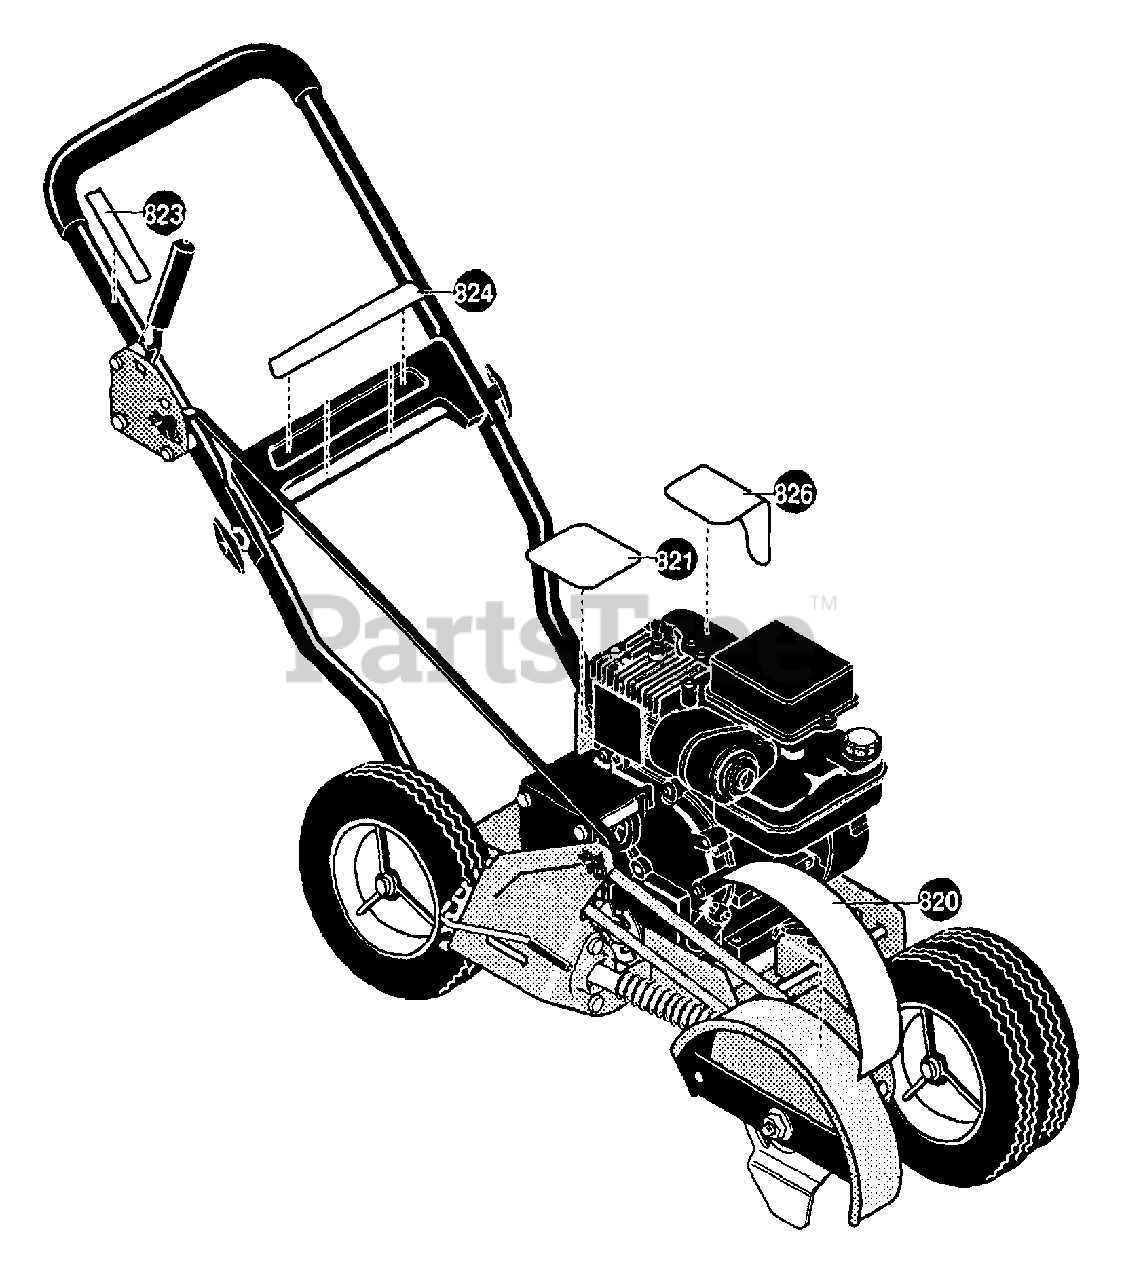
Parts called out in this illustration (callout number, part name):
820	DECAL, BLADE GUARD
821	DECAL, INFORMATION !DANGER!
823	DECAL, CLUTCH
824	DECAL, HUSQVARNA LE309
824	DECAL, "HUSQVARNA"
